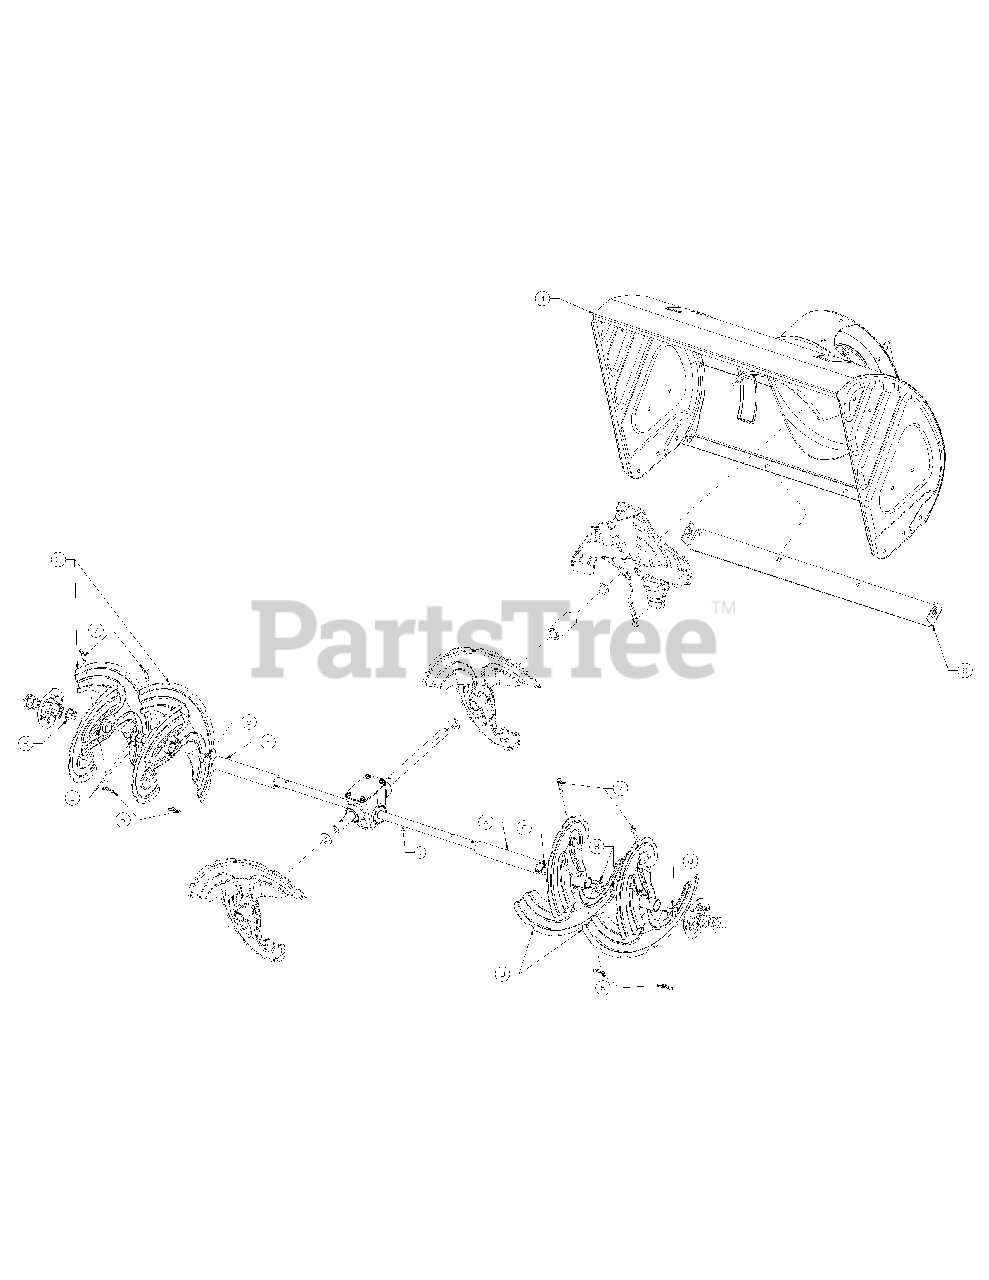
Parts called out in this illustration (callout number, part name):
1	Gearbox Asm-Aug
5	Pin-Cotter
6	Spacer
7	Pin-Shear .25
8	Flange Bearing
